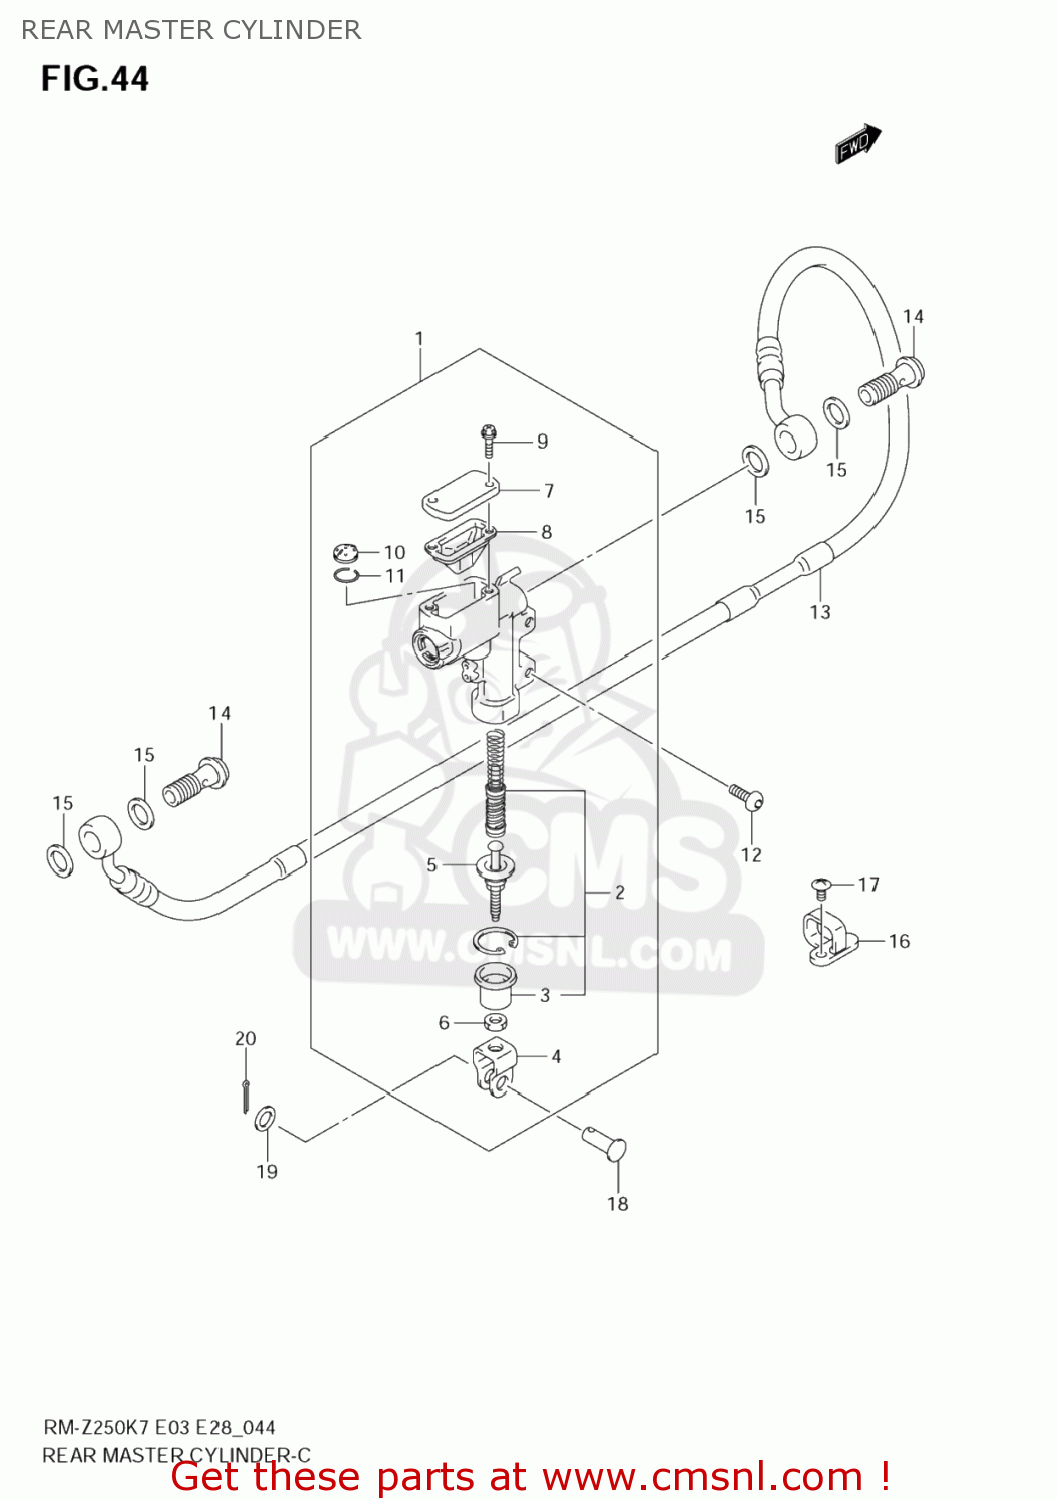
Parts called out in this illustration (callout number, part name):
1	CYLINDER ASSY,RR MASTER
2	PISTON / CUP S
3	BOOT
4	YOKE
5	ROD,PUSH
6	NUT
7	CAP
8	DIAPHRAGM
9	SCREW
10	SEPARATOR
11	RING
12	SCREW(6X16)
13	HOSE, REAR BRAKE
14	BOLT UNION
15	WASHER(10X15X1.5)
16	GUIDE,RR BRAKE
17	SCREW
18	PIN(8X20)
19	WASHER(8.5X14X1.6)
20	PIN
